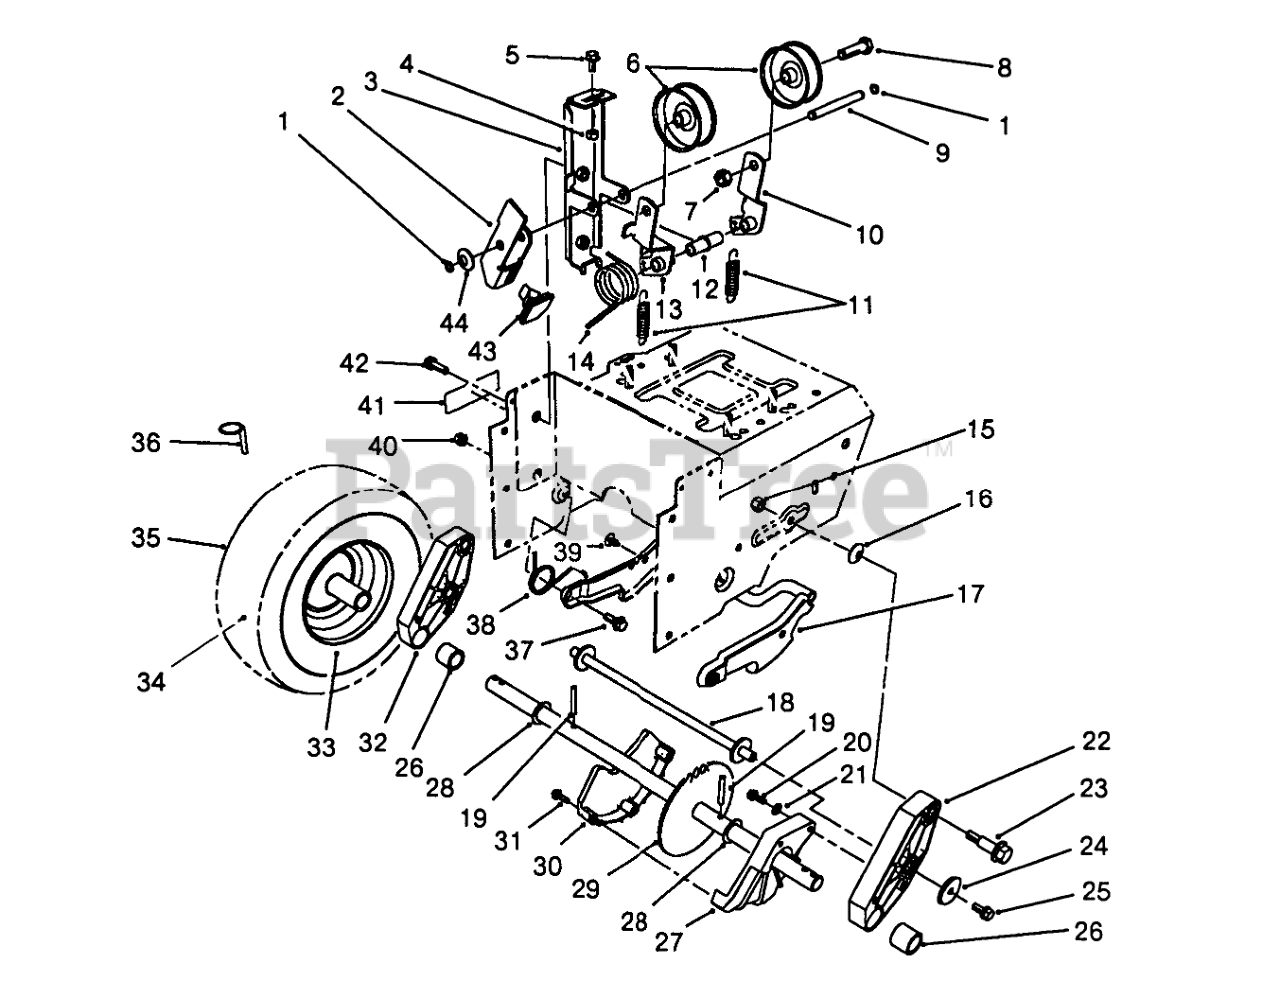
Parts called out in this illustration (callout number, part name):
1	RING-RETAINING
2	ARM-BRAKE
3	IDLER ARM BRACKET ASM
4	NUT-LOCK, NI
5	SCREW-HHF
6	PULLEY-IDLER
7	NUT-LOCK, NI
8	SCREW-HH
9	PIN-IDLER
10	ARM-IDLER, TRACTION
11	SPRING-EXTENSION
12	BUSHING-IDLER
13	ARM-IDLER, IMPELLER
14	TORSION SPRING
15	NUT-LOCK, NI
16	WASHER-SPRING
17	Latch-Arm
18	PIVOT TUBE WA
19	PIN-ROLL, SLOTTED
20	SCREW-HWH
21	WASHER-FLAT
22	Pivot Arm Assembly L.H. (Incl. Ref. #26)
23	BOLT-SHOULDER
24	WASHER
25	SCREW-TAPTITE
26	BUSHING-AXLE
27	GUARD-CHAIN, LH
28	WASHER-THRUST
30	GUARD-CHAIN, RH
31	SCREW-PPH
32	Pivot Arm Assembly R.H. (Incl. Ref. #26)
33	WHEEL RIM
34	INNER TUBE
36	PIN-LYNCH
37	SCREW-SHOULDER
38	SPRING-LATCH, TORSION
39	FASTENER-PANEL
40	NUT-LOCK, NI
41	DECAL-WARNING
42	SCREW-HHF
43	Brake Pad
44	WASHER-CURVED
